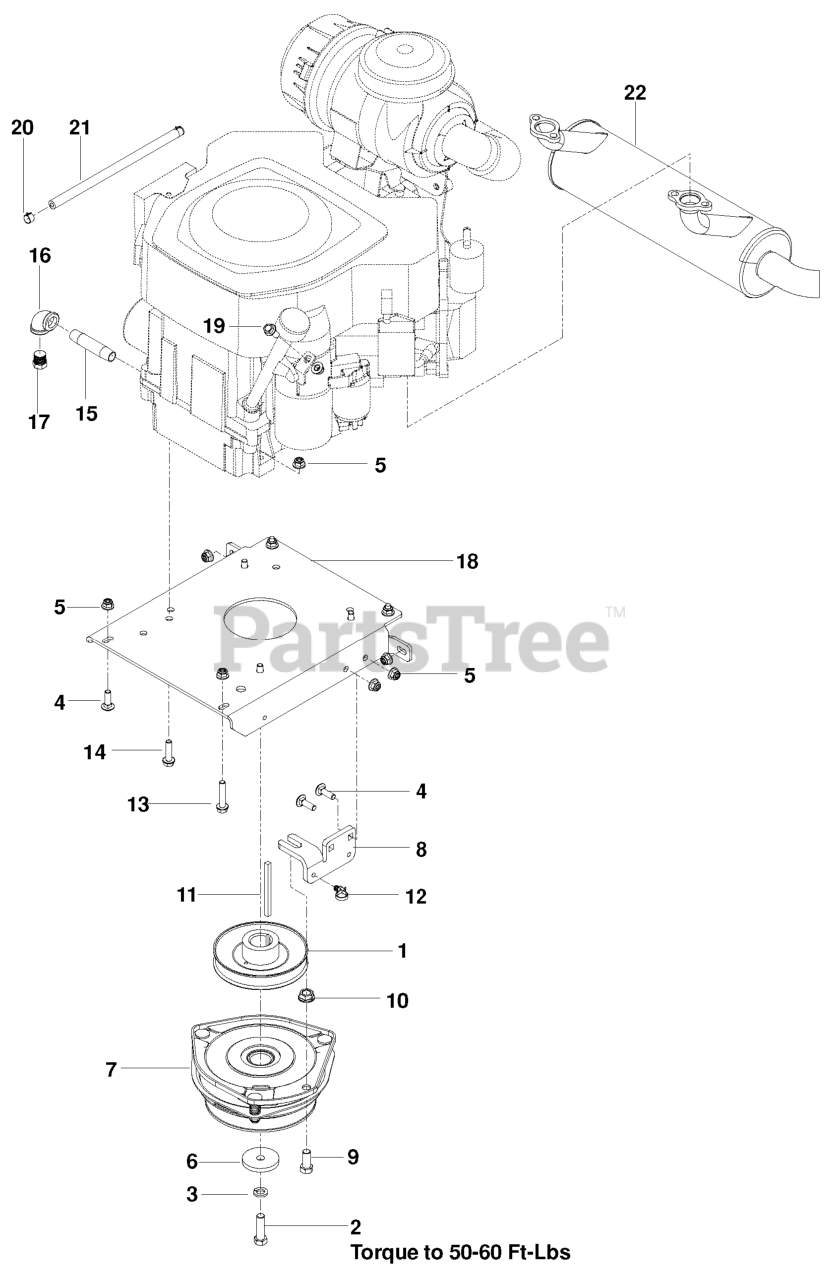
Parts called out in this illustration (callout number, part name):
1	PULLEY, ENGINE
2	HCS 7/16F X 1 1/2
3	WASHER 7/16 LOCK
4	RHSNB 5/16C X 1
5	5/16-18 NYLOC FLANGE NUT
6	BLADE WASHER
7	CLUTCH, GT3.5
8	STOP, CLUTCH, OGURA
9	HCS 7/16-14 X 1 GR 5 ZD
10	NUT 7/16C WHIZ
11	KEY, 1/4 SQ X 3.5
12	TIE WRAP, 8-3/8", W/CLIP
13	HHFS 5/16-18 X 2.25 GD 5
14	HHFS 5/16-18 X 1.5 GD 5
15	PIPE NIPPLE 3/8 X 3
16	90 DEG.ELBOW 3/8NPT
17	PLUG, DRAIN 3/8 NPTF
18	PLATE.ENGINE.BLACK
19	HHFS 5/16-18 X 3/4
20	HOSE CLAMP
21	FUEL LINE 5"
22	MUFFLER.CV23.THRU.CV30
